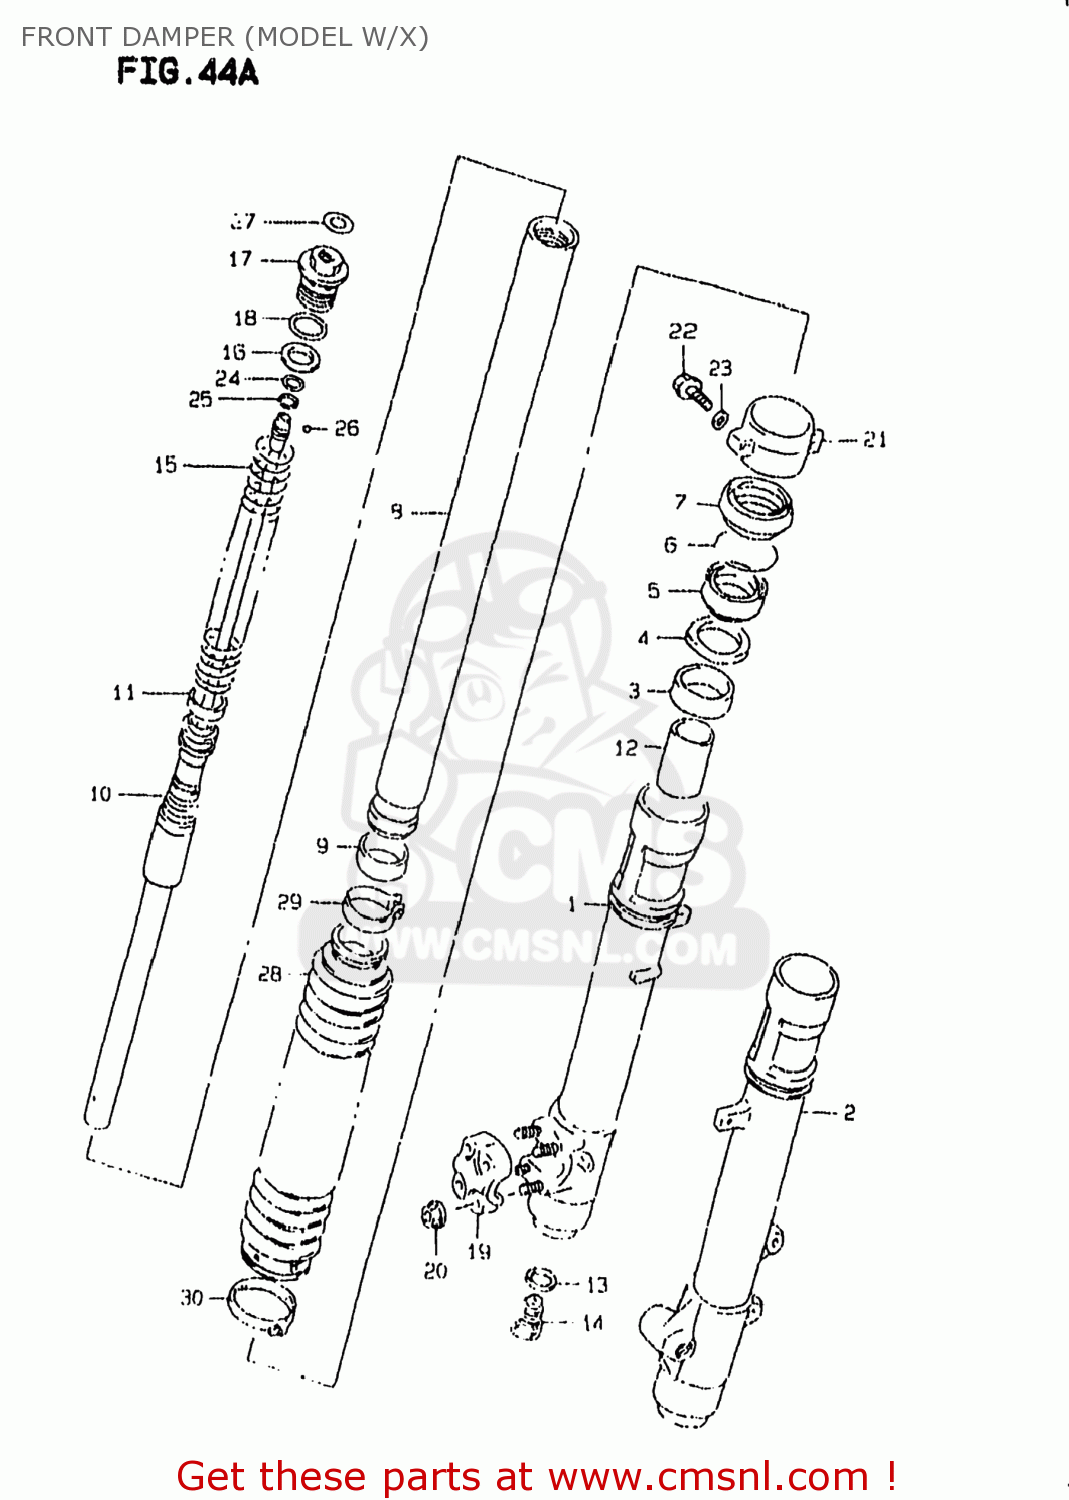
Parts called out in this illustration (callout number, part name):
0	DAMPER ASSY,FR FORK,L
1	TUBE,OUTER,RIGHT
2	TUBE,OUTER,LEFT
3	BUSH,GUIDE
4	SPACER,SEAL
5	SEAL,OIL
6	CIRCLIP,FORK OIL SEAL
7	DUST SEAL
8	TUBE,INNER
9	BUSH,SLIDE
10	SPRING,FRONT
11	BUSH,SLIDE
12	PIECE,OIL LOCK
13	GASKET (NAS)
14	BOLT,CTR
15	SPRING,FRONT
16	SEAT,SPRING LWR
17	BOLT,FORK
18	O RING
19	HOLDER,AXLE
20	NUT
21	HOLDER
22	BOLT
23	WASHER(5.5X10X1)
24	O RING(D:2.5,ID:13.8)
25	EXPANDER
26	BALL
27	LABEL (TEN S-H)
28	BOOT
29	BAND,BOOT UPR
30	BAND,BOOT LWR
